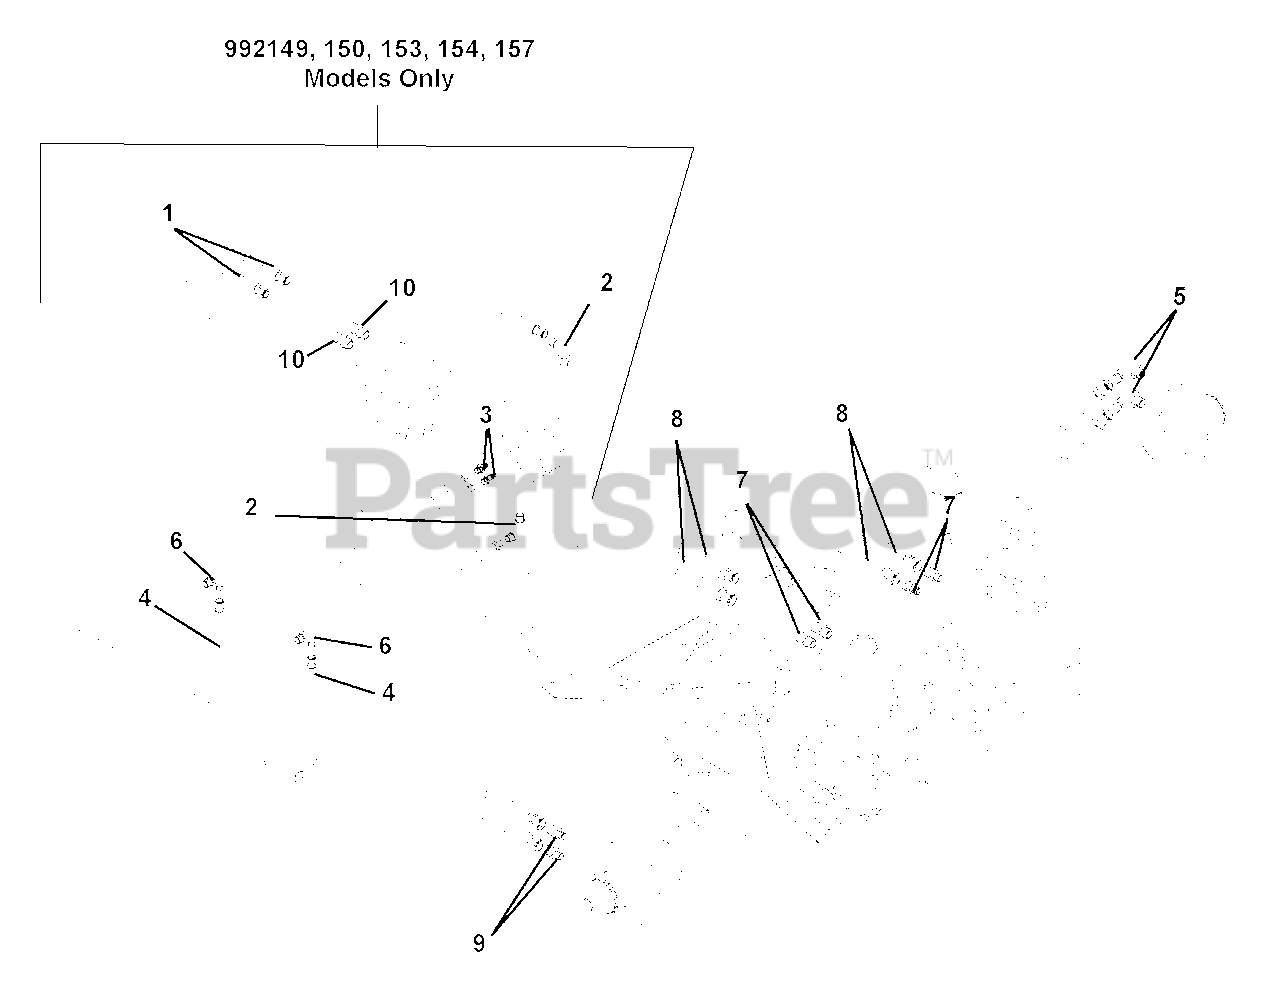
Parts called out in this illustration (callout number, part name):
1	Hose, Hydraulic
2	Hydraulic, Fitting Elbow
3	Adapter
4	Hose, Hydraulic
5	Fitting, Hydraulic
6	Fitting, Hydraulic
7	Adapter, Face Seal 8 x 8 .50 O-Ring
8	Hose, Hydraulic .50
9	Adapter, Hydraulic Steel
10	Fitting, Hydraulic
